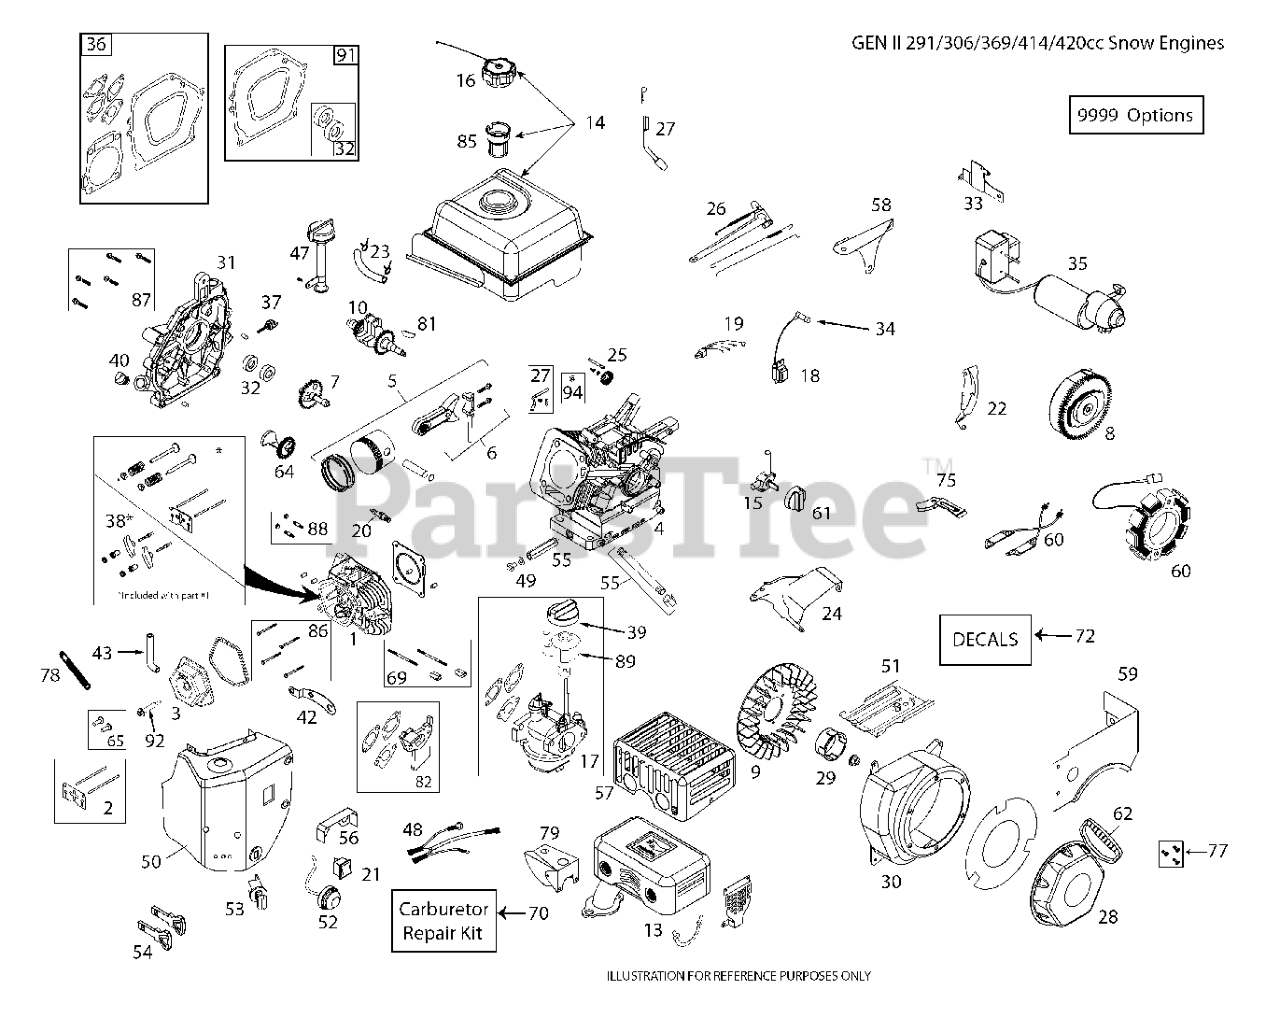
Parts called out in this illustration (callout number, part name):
1	CYLINDER.HEAD.ASSY(SK2911000)
2	PUSH ROD TAPPET KIT
3	VALVE.COVER.LCT.414CC.
4	CYLINDER ASSY SNO.LCT
5	PISTON.AND.ROD.ASSY(SK2911400)
6	CONNECTING ROD ASSY SNO.LCT
7	CAMSHAFT.LCT.291CC
8	FLYWHEEL.EL.ST.SKSNO2401.1
9	FLYWHEEL.FAN
10	CRANKSHAFT
13	MUFFLER ASSY LCT SNO
14	FUEL TANK ASSY - SNOW (291CC)
15	FUEL.PETCOCK.SNOW(SKSN4900)
16	FUEL.TANK.CAP.SNOW(SKSN4301)
17	CARBURETTOR LCT
18	COIL.IGN.CDI.SKSN2403.1
20	SPARK.PLUG(SK2911550)
21	ON/OFF.SWITCH.SNOW(SKSN4403)
23	FUEL HOSE KIT
24	TOP.SHIELD.LCT.
25	GOVERNOR.GEAR.ASSY(SK2912900)
26	GOVERNOR.ARM.ASSY.(SKSN2502)
27	GOVERNOR.SHAFT.(SK2913100)
28	STARTER RECOIL.291/306CC.LCT
29	STARTER CUP.LCT.291/306CC
30	BLOWER HOUSING.LCT.291/306CC W
31	CRANKCASE.COVER.ASY(SK2913600)
32	OIL.SEAL.KIT(SK2913900)
33	SWITCHBOX BRACKET ES LCT 291 S
34	SPARK.PLUG.BOOT.SNW,SKSN4691.1
35	STARTER, ELECTRIC, 230V
36	ENGINE.GASKET.KIT(SK2914300)
37	DIPSTK.OIL.BLK.LCTSK4143711.1
38	ROCKER ARM KIT
39	CHOKE.KNOW.SNOW(SKSN4500)
40	NONREMVABLE.OIL.PLUG(SK4143715
42	CDI.BOX.BRKT.SNOW(SKSN4402)
43	BREATHER TUBE LCT 291/369/414
47	HIGHOIL.FILL.ASSY.KIT(SKSN4911
48	WIRE.HARNESS(SKSN4406)
50	HEATER.BOX.ASSY.SNOW(SKSN2100)
51	SHIELD.CYLINDER.SNOW(SK4141010
52	PRIMER.BULB.ASSY(SKSN4304)
53	KEY.SWITCH.ASSY.SNOW(SKSN4401)
54	KEY SET(2 KEYS) SKSN0407.1
55	OIL PIPE DRAIN EXTENDED.LCT SK
56	SHIELD.VAPOR(SKSN4606)
58	GOVERNOR.LINK.SHIELD(SKSN2501)
59	FUEL TANK SKIRT.LCT.291/306CC
60	ALTERN.60WATT.SKSN2402.1
61	FUEL KNOB-SNOW
62	HANDLE.RECOIL.DELUXE.LCT
65	TAPPET KIT.LCT.SK2911005.1
69	STUD.CARB.MOUTING.KIT.291CC
70	CARBURETTOR REPAIR KIT 291CC/4
75	WIRE GUARD
77	BOLT.KIT.RECOIL.LCT.ALL.ENGINE
79	SHIELD CARBURRETOR COVER 414
81	KEYS.FLYWHEEL.136/291CC.5PACK
82	SPACER.CARBURETOR.291CC.LCT
85	STRAINER.FUEL.TANK.LCT.208CC
86	KIT.BOLT.CYLINDER.HEAD.(4PC)
87	KIT.7-BOLT.CRANKCASE.CVR.291CC
88	STUD.MUFFLER.KIT.LCT
89	KNOB LCT.SKSN5325.1 SPEED
91	GASKET KIT CRANKSHAFT.LCT
92	CENTER VALVE COVER BOLT
9999	HIGH.ALTITUDE.JET.6000FT ANDUP
9999	KIT.BOLT.LCT.SK9990.1
